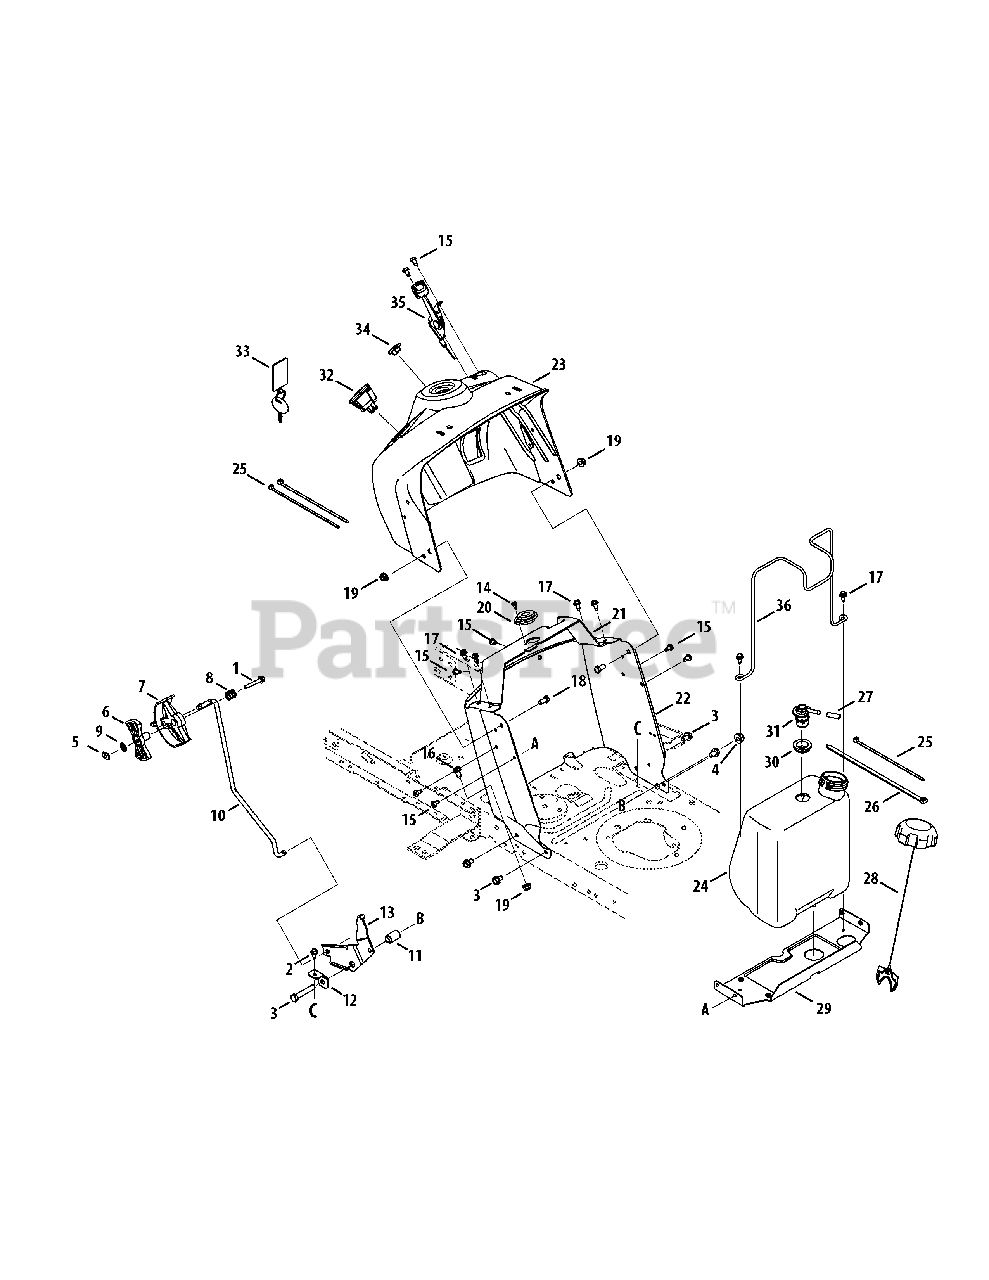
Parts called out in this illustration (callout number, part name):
1	Hex Head Screw, 1/4-20 x 1.50
2	Self-Tap Screw, 1/4-20 x .625
3	Hex Head Screw, 3/8-16 x 2.00
4	Flange Lock Nut, 3/8-16
5	Top Lock Weld Nut, 1/4-20
6	Index Control
7	Shift Lever
8	Compression Spring, .685 x .63
9	Internal Lock Washer, 1/4
10	Speed Control Rod
11	Flange Spacer, .390 x .671 x 1.095
12	Speed Latch Tab
13	Transmission Speed Latch, RMC
14	Screw, #10
15	Self-Tap Screw, 1/4-20
16	Self-Tap Screw, 5/16-18
17	Hex Washer Screw, 1/4-20 x .625
18	Hex Head Screw, 5/16-18
19	Flange Lock Nut, 5/16-18
20	Steering Column Bearing
21	Steering Support Bracket
22	Lower Dash
23	Upper Dash Panel
24	Fuel Tank
25	Cable Tie, 3/16 x 7.4"
26	Cable Tie, 36" Lg.
27	Vent Hose
28	Fuel Cap
29	Gas Tank Support Bracket
30	Rubber Grommet
31	Fuel Rollover Valve
32	Key Switch Module
33	Key Assembly
34	Choke Plug
35	Throttle/Choke Assembly
36	Fuel Tank Support Rod
